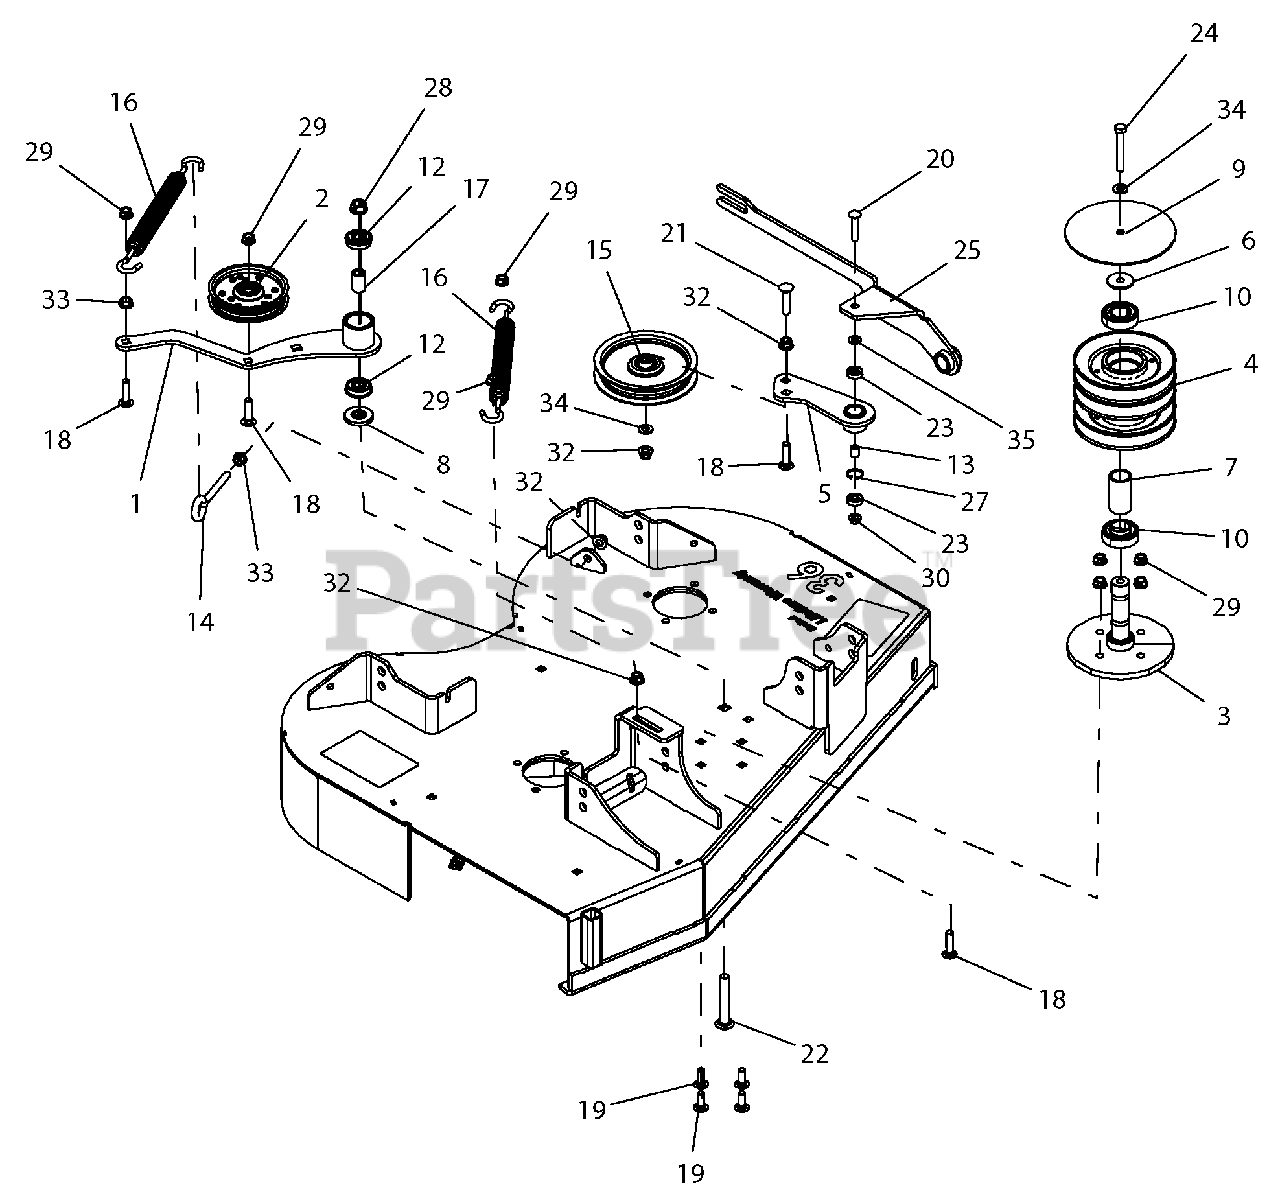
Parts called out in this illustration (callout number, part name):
1	WLDMT, IDLER DECK DRIVE
2	ASM, IDLER 4"
3	WLDMT, JACKSHAFT BASE
4	WLDMT, JACKSHAFT HOUSING
5	WLDMT, IDLER ARM
6	RETAINER, JACKSHAFT SPINDLE
7	SPCR, BRG SPINDLE
8	SPACER, IDLER ARM
9	PLATE, JACKSHAFT COVER-BLACK
10	BRG., RG 1.00 X 2.0467 X .591
12	BRG, BALL .501 X 1.38 X .438 SEALED
13	BSHG, SLV .330X.455X.550
14	BOLT, EYE .38-16X4.50 .75 DIA
15	IDLER, FLAT 5.00 X 3.8
16	SPRG, EXTENSION
17	SPACER, .510 X .750 X 1.148
18	BLT-RDHDSQNK .38-16X1.50 G5 Y
19	BLT-RDHDSQNK .38-16X1.00 G5 YWZC
20	BLT-RDHDSQNK .31-18X1.75 G5 YWZC
21	BLT-RDHDSQNK .38-16X1.75 G5 YWZC
22	BLT-RDHDSQSHNK .50-13X3.25 YWZC
23	BRG-BALL .315X.866X.276 (608)
24	BLT-HEX .38-16X2.75 GR8 YWZC
25	WLDMT, PIVOTING IDLER
27	RING, RETAINING-INTERNAL .875"
28	NUT-LK-CTR-FLG .50-13 YWZC
29	NUT, LK-CTR-FLG .38-16 YWZC
30	NUT, LK-CTR-FLG .31-18 YWZC
32	NUT-LK-NYL-FLG .38-16 YWZC
33	@NUT-SPNLK-FLG .375-16 YWZC
34	WSHR-FL-STL.406X.812X.065 YWZ
35	WSHR-FL-STL.344X.688X.065YWZC
